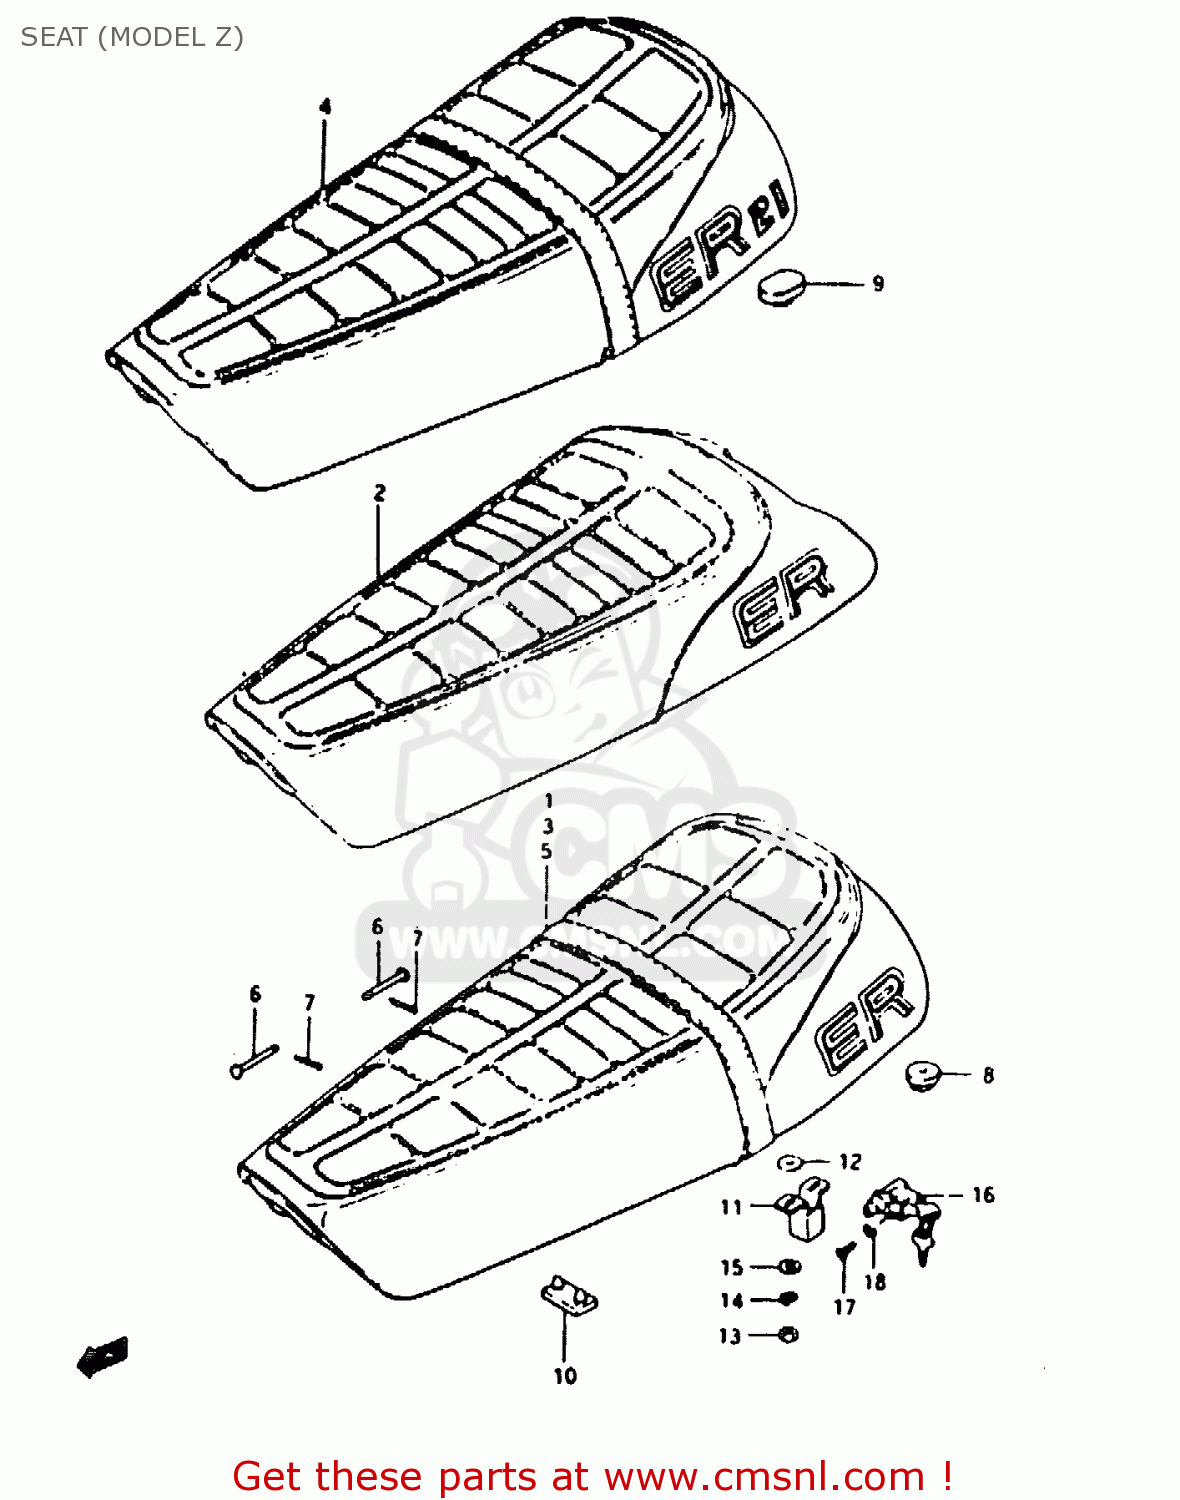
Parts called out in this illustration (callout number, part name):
1	SEAT ASSY (BLACK)
6	PIN
7	PIN
8	CUSHION
10	CUSHION
11	PLATE,CLAMP GUIDE
12	WASHER(8.5X18X1)
13	NUT
14	LOCK WASHER
15	WASHER
16	LOCK ASSY,SEAT
17	SCREW
18	LOCK WASHER
